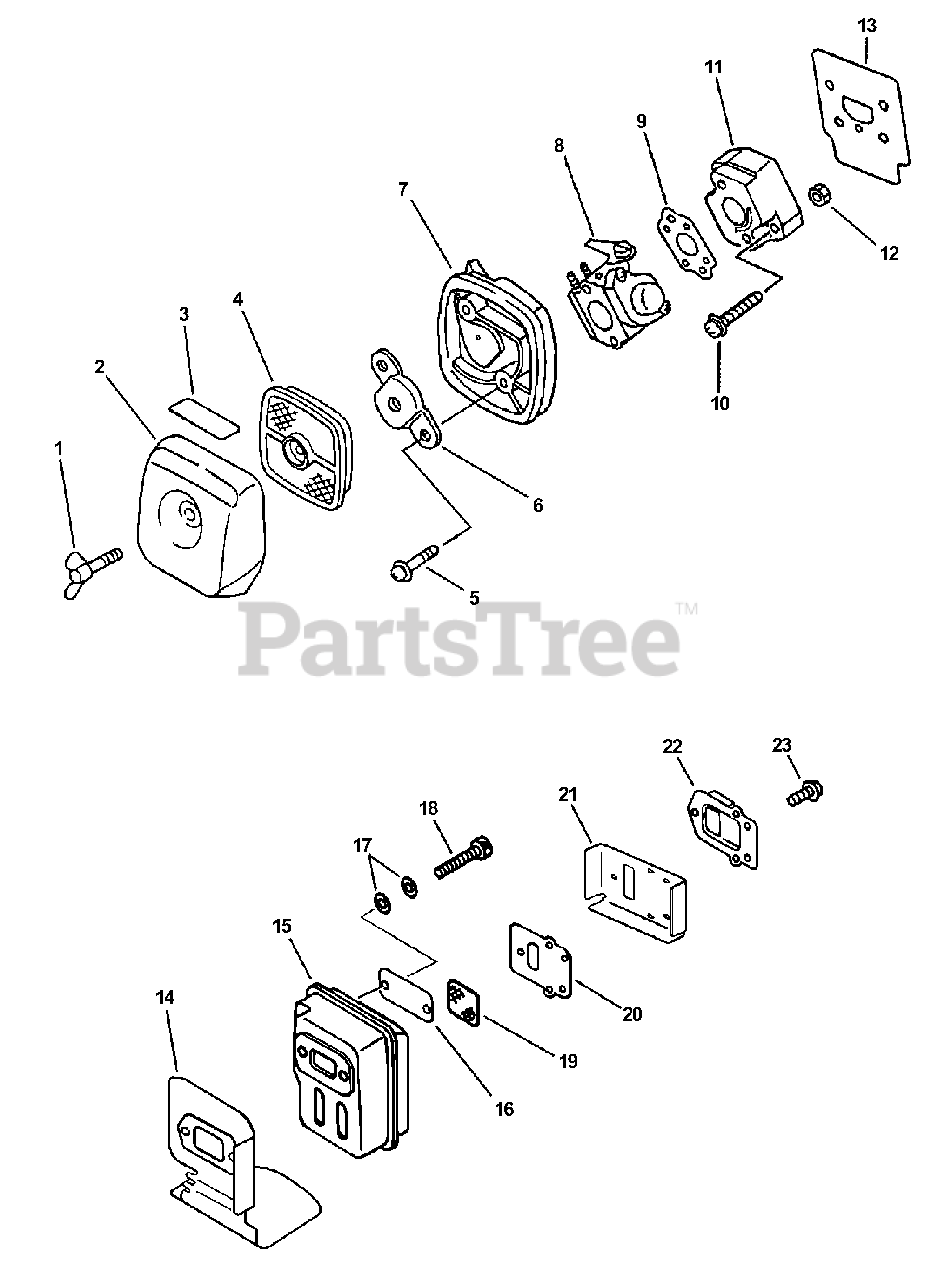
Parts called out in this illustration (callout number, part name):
1	BOLT, WING 5×20
2	COVER, AIR FILTER - GRAY
3	LABEL, CHOKE
4	FILTER, AIR - SINGLE LAYER
5	SCREW 5×65
6	PLATE, PREVENT
7	CASE, AIR FILTER - GRAY
8	CARBURETOR - C1U-K58
9	GASKET, INTAKE
10	SCREW 5×20
11	INSULATOR, INTAKE
12	NUT M5
13	HEAT SHIELD, INTAKE
14	SHIELD, EXHAUST
15	MUFFLER
16	PLATE, EYE
17	CONICAL WASHER
18	BOLT 5×55
19	SCREEN, SPARK ARRESTER
20	GASKET, EXHAUST
21	GASKET, EXHAUST
22	GUIDE, EXHAUST
23	SCREW 4×10
